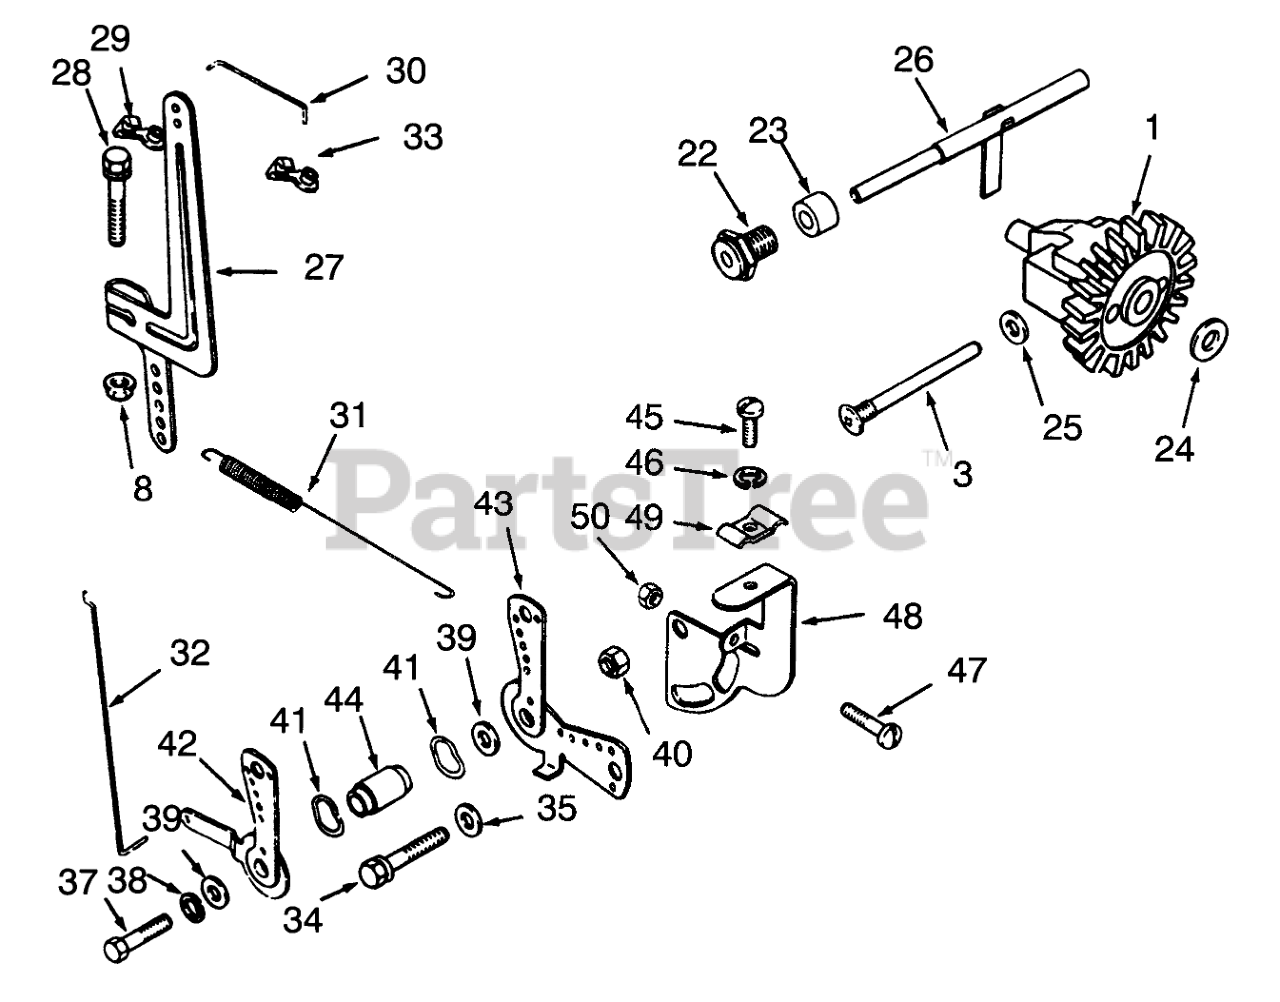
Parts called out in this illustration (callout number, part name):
1	Kit-Governor Gear (Incl. Ref. #24)
3	Govenor Stop Pin
8	Palnut
22	Bushing
23	Spacer
24	Washer
25	Washer
26	Kit-Governor Cross Shaft
27	Governor Lever
28	Screw
29	Bushing
30	Carburetor Linkage
31	Spring (Governor to Cab.)
32	Choke Linkage (Carb. to Choke Shaft)
33	Bushing
34	Screw
35	Washer
37	Screw
38	Washer-Lock
39	Washer
41	Washer
42	Choke Control Lever
43	Lever-Throttle Control
44	Space
45	Screw
46	Washer
47	Screw
48	Bracket-Clutch Control
49	Clamp
